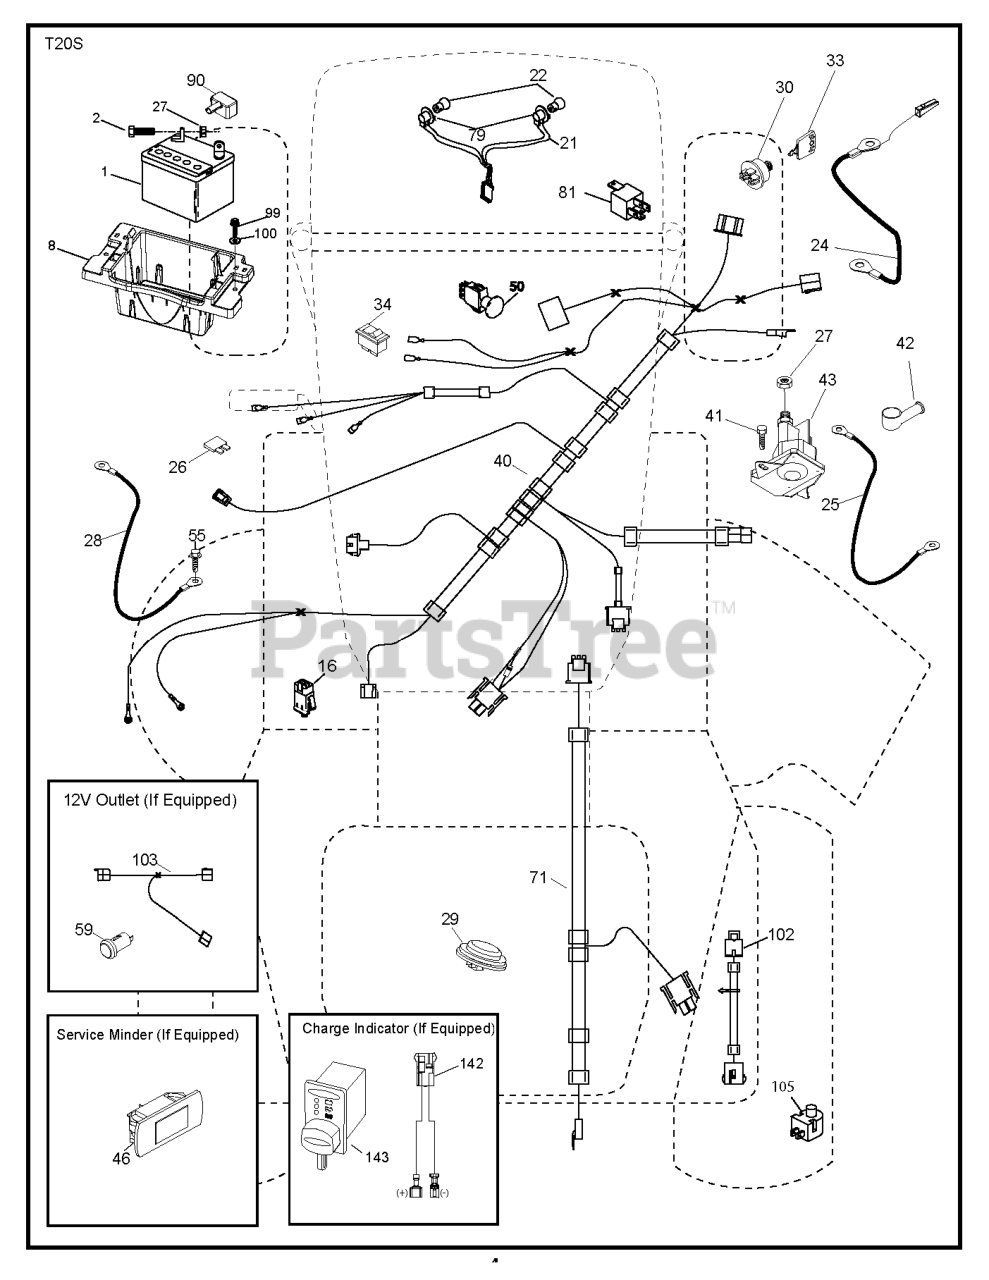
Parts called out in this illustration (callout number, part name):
1	Battery 12 Volt 25 Amp
2	BOLT.HEX.1/4.X.3/4.DICHROMATE
8	TRAY.BATTERY BOX.FRONT
16	SWITCH INTERLOOK PUSH-IN
21	HARNESS.LIGHT W/4152J BULBS
24	CABLE.FRBATT.W/WIRE.8GA.8
25	CABLE.STARTER.8GA.17.5
26	FUSE 20AMP
27	NUT
28	CABLE.GROUND.21"BLK.8GA.90T
29	SWITCH.SEAT.DELTA.OPC.
30	SWITCH.IGN.DELTA.W.LGH.ROS
33	KEY.CHAIN.BLISTER.PACK.GEN.USA
40	HARNESS.IGN.ELEC.RELAY.TEX.46"
41	SCREW
42	TERMINAL COVER
43	SOLENOID.W/BRASS.PLUNGER
46	RP.GUAGE.SRVCMNDR.HRMTR.
50	RP.PTO.SWITCH.8 TERMINAL.BLACK
55	SCREW 5/16"
59	OUTLET.12-VOLT
71	HARNESS-CHASSIS SUB
79	BULB HOLDER ASM.
81	RELAY HARNESS.SEALED
90	COVER.TERMINAL.BATTERY
99	SCREW HEXWSHR 1/4-20X3/4
102	HARNESS PIGTAIL PCH TEX ROS
103	HARNESS PIGTAIL 12V OUTLET
105	REVERSE SWITCH
142	CHARGE.PORT.PIGTAIL HARNESS
143	CHARGE.PORT
